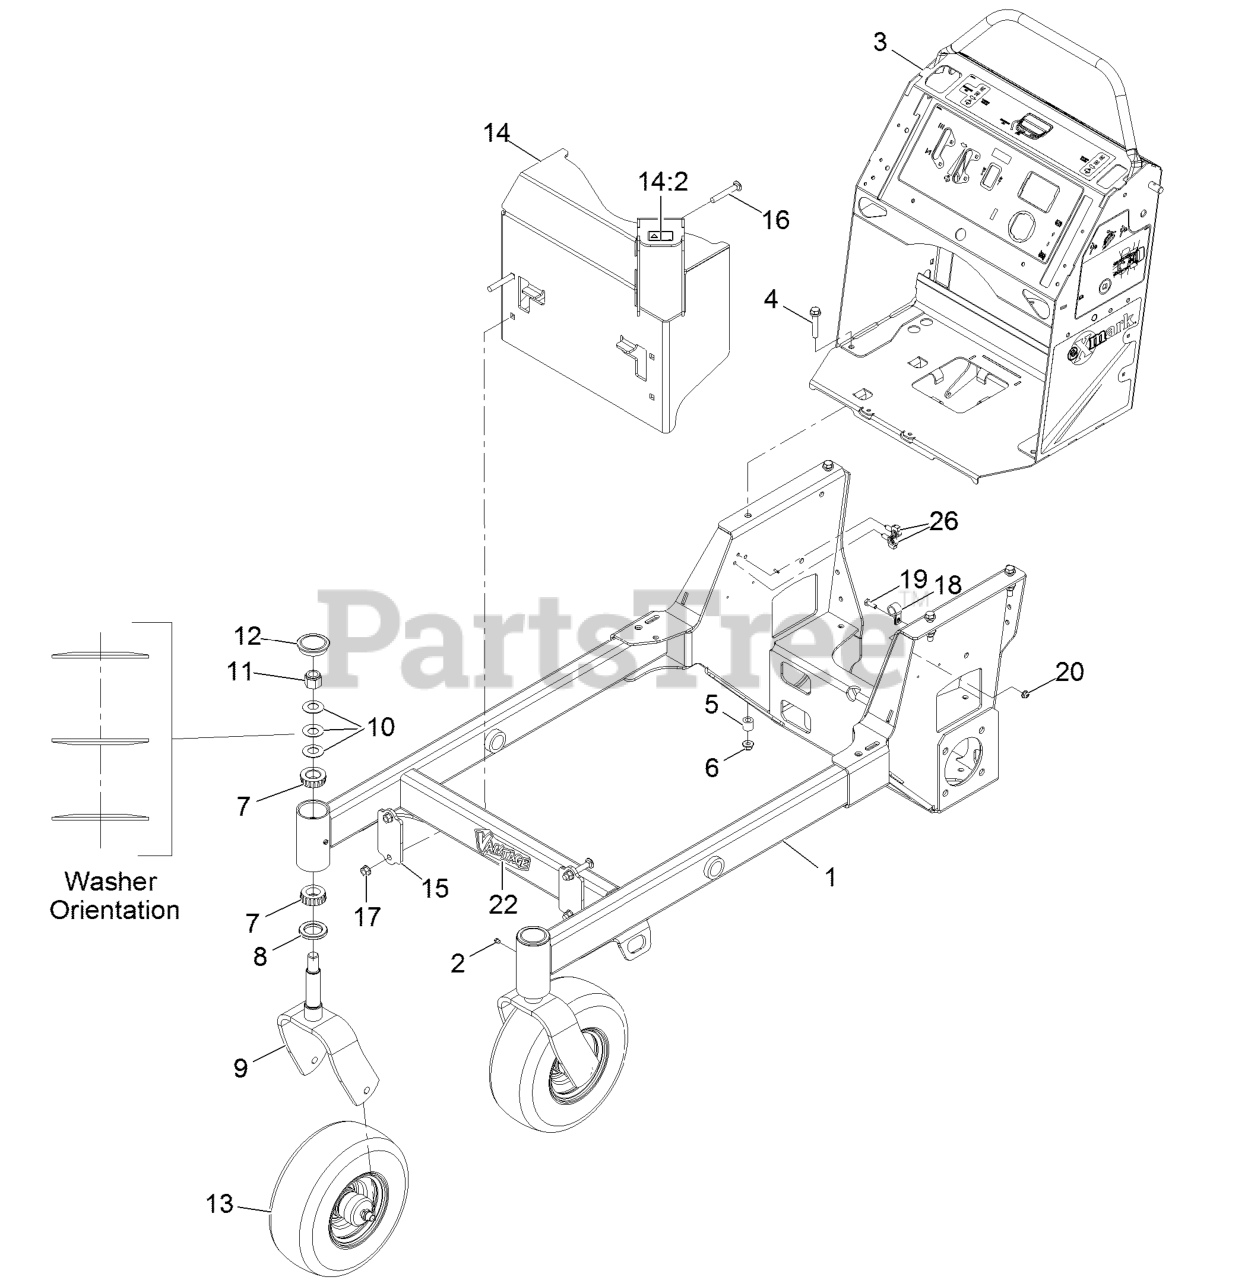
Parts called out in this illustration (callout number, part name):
1	FRAME ASM
3	CONTROL TOWER ASM
4	SCREW-HHF
6	NUT-HF, NI
7	Cone-Bearing Tapered Roller
8	SEAL-GREASE
9	FORK-CASTER
10	WASHER-BELLVILLE
11	NUT-LOCK, NI
12	CAP-GREASE
13	WHEEL/TIRE AND BEARING AS
14:2	DECAL-WARNING
15	BRACKET-MOUNTING, GUARD
16	SCREW-CARR
18	CLAMP-CABLE
19	SCREW-HH
22	DECAL-VANTAGE LOGO
26	CLIP-HARNESS
